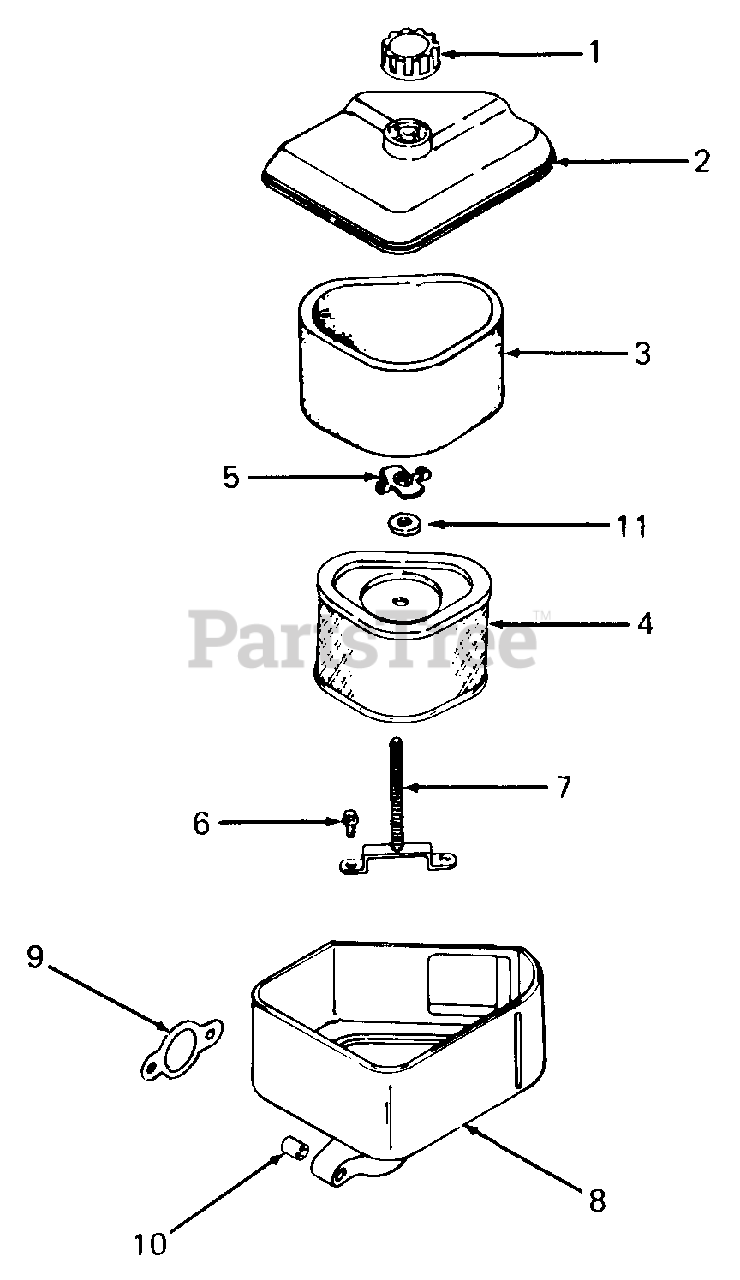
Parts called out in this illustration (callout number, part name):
1	Knob, Air Cleaner Cover
2	Cover, Air Cleaner
3	Precleaner, Element
4	Element, Air Cleaner
6	Screw, Mtg Plate Stud
7	Stud, Mounting Plate
8	Base, Air Cleaner
9	Gasket, Air Cleaner
11	Washer, Plain, 1/4
